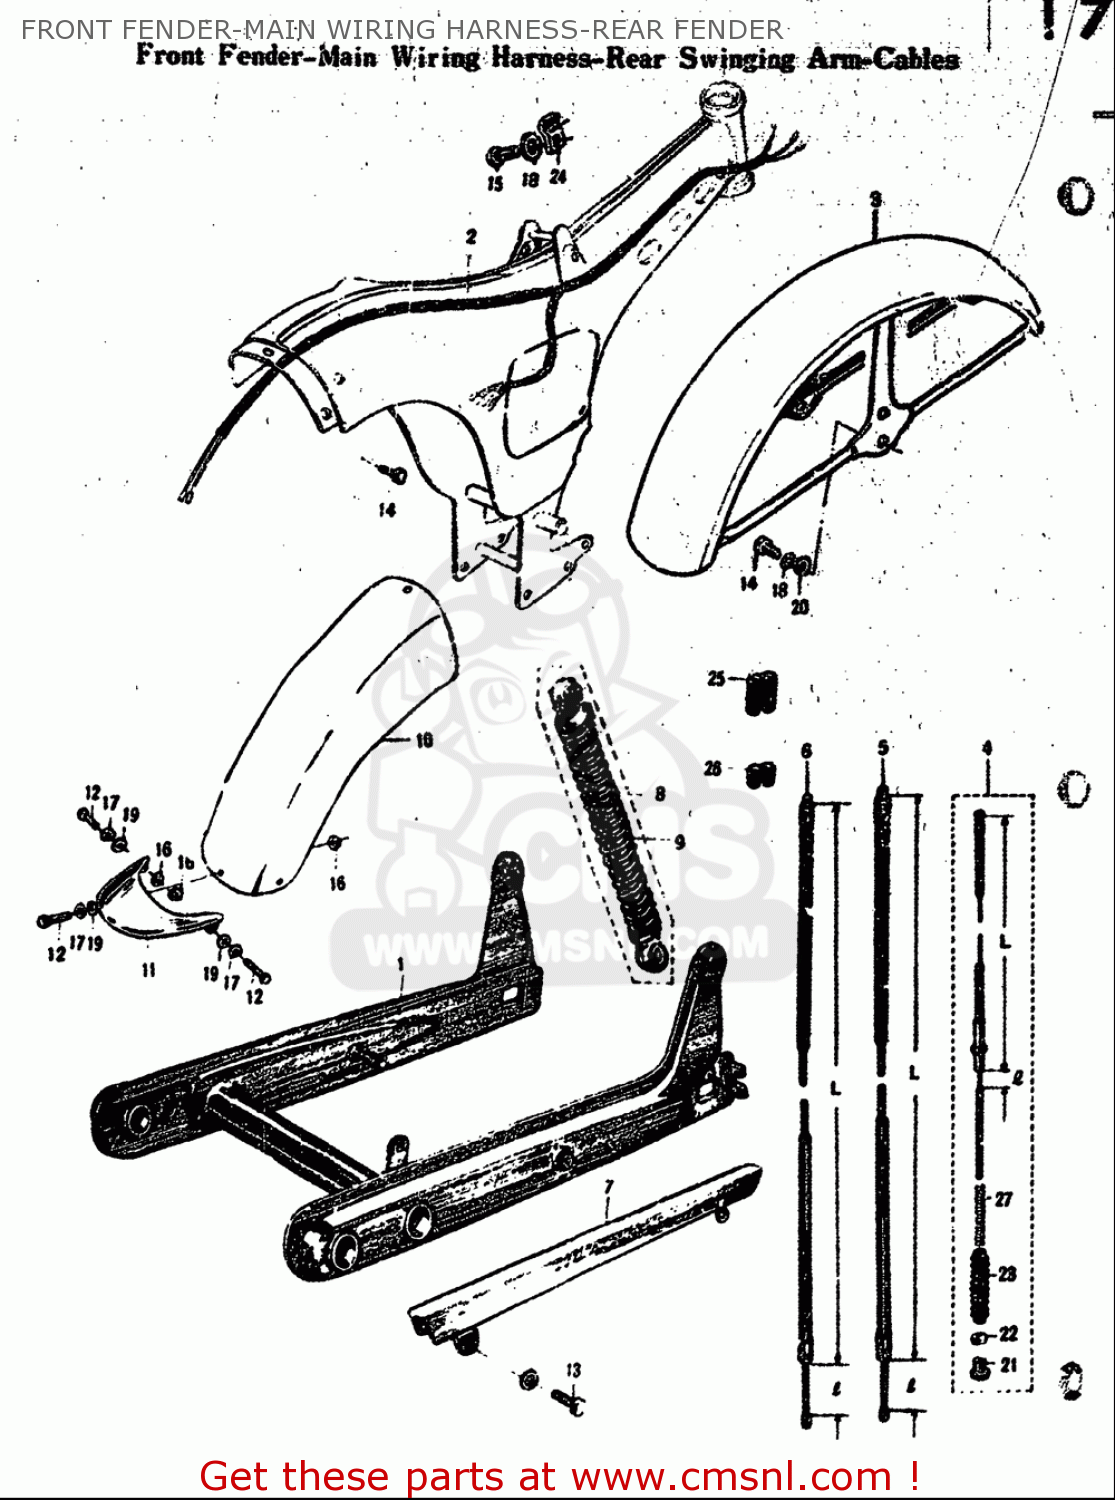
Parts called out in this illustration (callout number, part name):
14	BOLT
16	NUT
17	WASHER,LOCK
18	WASHER,LOCK
19	WASHER
20	WASHER
21	NUT
22	BRAKE ROD LEVER
23	SEAL,DUST(7X16X75)
25	CLIP
26	CLIP
27	SPRING
